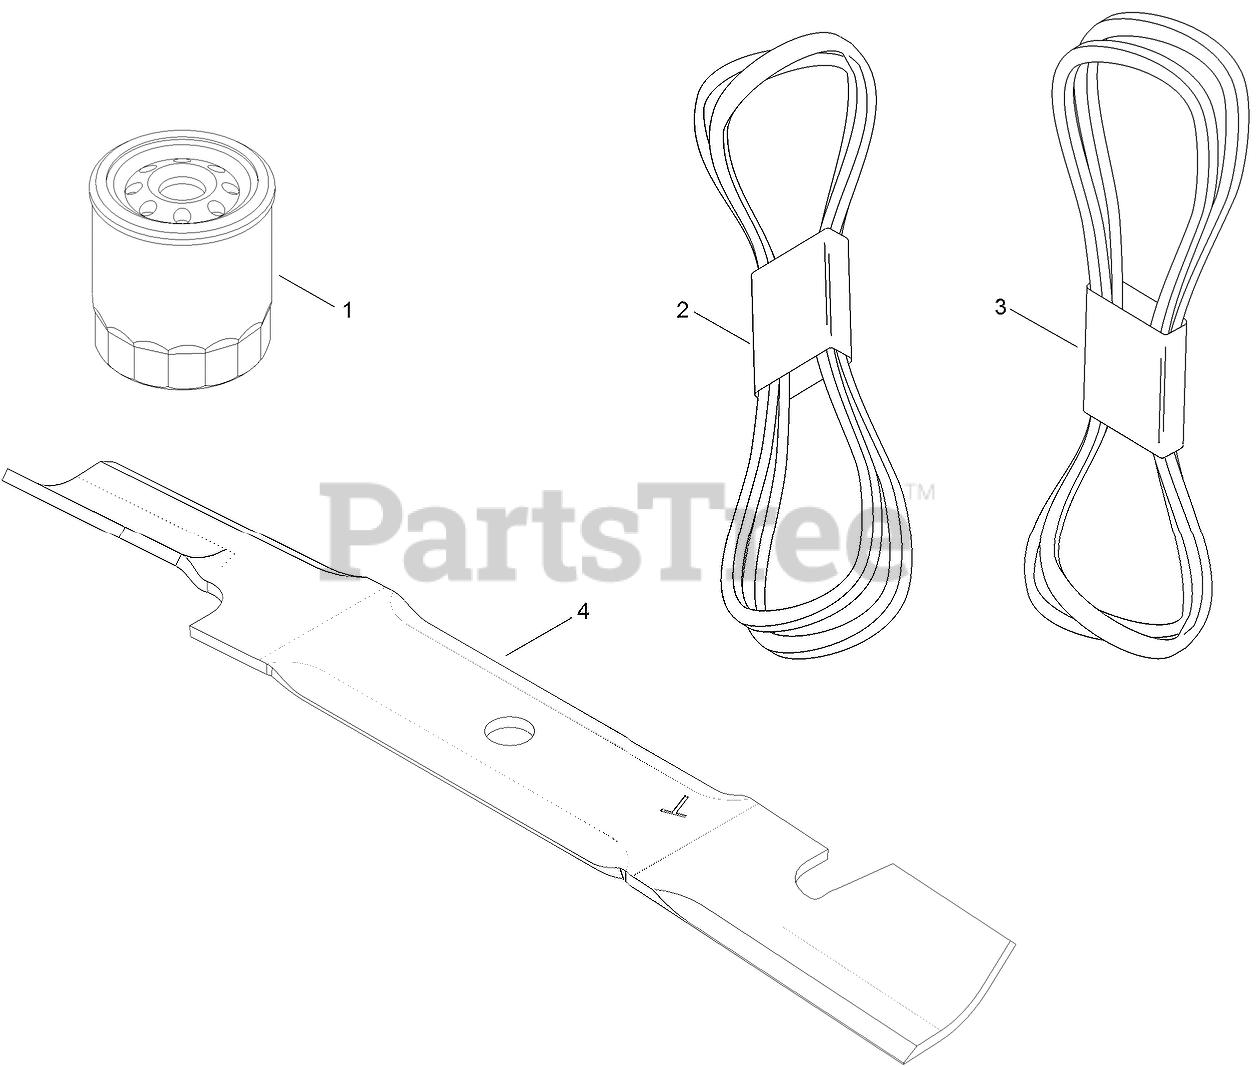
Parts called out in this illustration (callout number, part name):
1	ELEMENT-OIL FILTER, HYD
2	V-BELT
3	V-BELT
4	BLADE-HI FLO, 16.50 INCH
